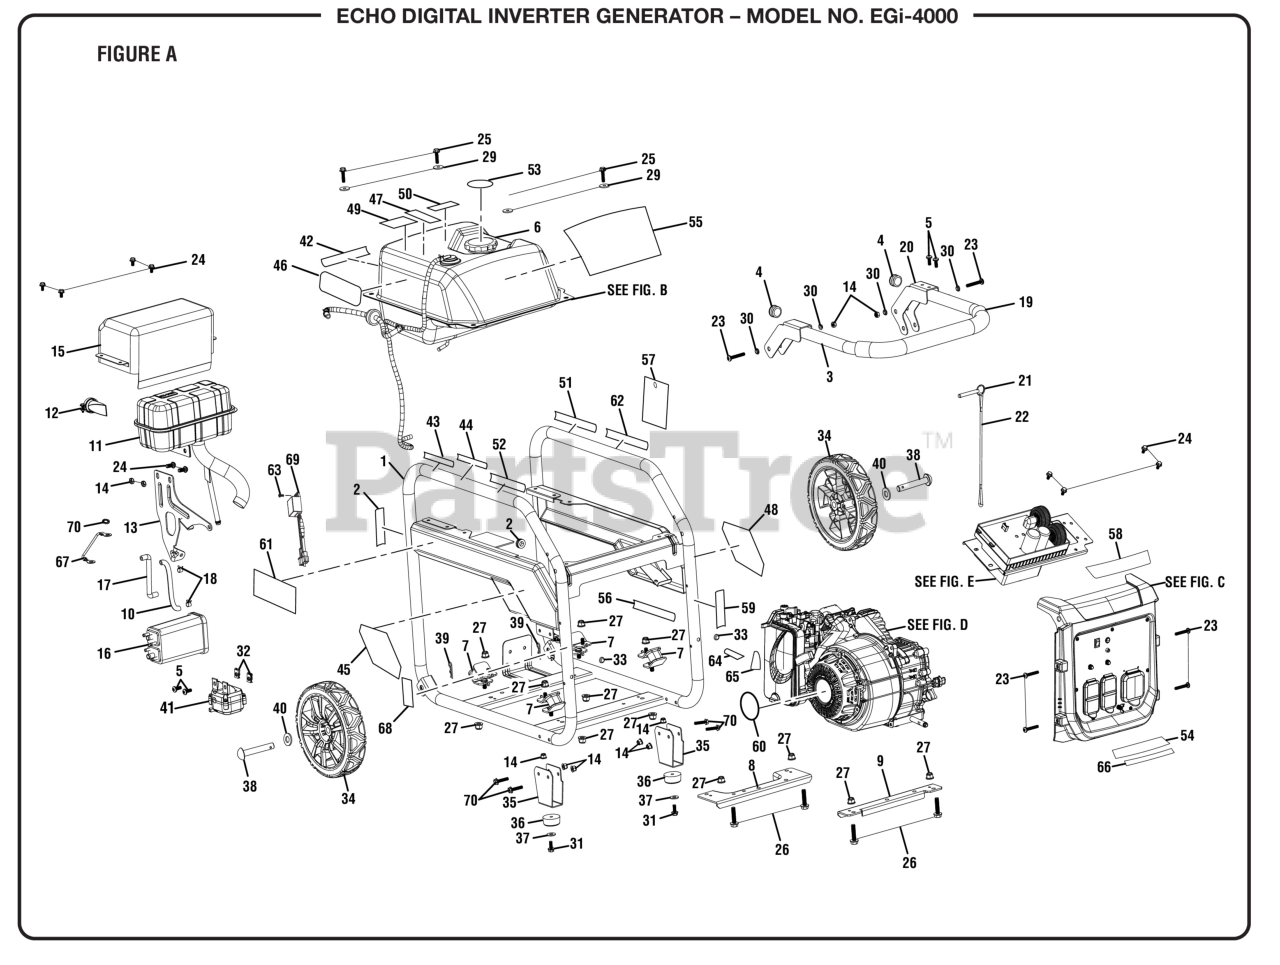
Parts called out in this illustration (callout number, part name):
1	ASSY., FRAME
2	LABEL, HOT SURFACE
3	ASSY., HANDLE W/ BRACKET
4	HANDLE, END CAPS
5	BOLT, T30 TORX
6	ASSY., FUEL TANK
7	ISOLATOR, 45 DEG
8	PLATE, ENGINE BOTTOM LEFT
9	PLATE, ENGINE BOTTOM RIGHT
10	HOSE, PAIR VALVE
11	MUFFLER W/ CATALYST
12	Spark Arrestor
13	BRACKET, MUFFLER
14	NUT, NYLON LOCK NUT
15	HEAT SHIELD, MUFFLER
16	CANISTER, CARBON REWIN
17	HOSE, CARBON CANISTER
18	CLAMP, FUEL HOSE
19	HANDLE, FOAM GRIP
20	HANDLE, RIGHT BRACKET
21	PIN, RELEASE
22	LANYARD, NYLON
23	SCREW, TORX PAN HEAD
24	BOLT, FLANGE HEX
25	BOLT, FLANGE HEX
26	BOLT, FLANGE HEX
27	NUT, NYLOC FLANGE
28	LABEL, HOT SURFACE
31	BOLT, FLANGE
33	BUMPER, HANDLE
35	BRACKET, FOOT METAL
36	WEAR PAD, RUBBER
39	PIN, HITCH
41	ASSY., CO DETECTOR
42	LABEL, HOT SURFACE
43	LABEL, INQUIRIES
44	LABEL, COMBUSTION
45	LABEL, CO MONITORING
46	LABEL, CO INSTRUCTION
47	LABEL, CPSC
48	LABEL, DANGER ICON
49	LABEL, E85
50	LABEL, EXHAUST DIRECTION
51	LABEL, FIRE DISTANCE
52	LABEL, FIRE DANGER
53	LABEL, FUEL STABILIZER (ENG)
54	LABEL, GROUND WARNING EN/FR
55	LABEL, PERFORMANCE
56	LABEL, LUBRICANT
57	LABEL, NOTICE
58	LABEL, COMMAND BLUETOOTH
59	LABEL, LOCKING PIN
60	LABEL, ECHO ENGINE RECOIL
61	LABEL, ECHO LOGO TANK
62	LABEL, FUEL STABILIZER (FR/SP)
63	BOLT, HEX FLANGED
64	LABEL, OFF
65	LABEL, ON
66	LABEL, FCC ID
67	ASSY., GROUND WIRE
68	LABEL, DO NOT TAMPER (FR)
69	REGULATOR (AC TO DC)
70	BOLT, FLANGE HEX
